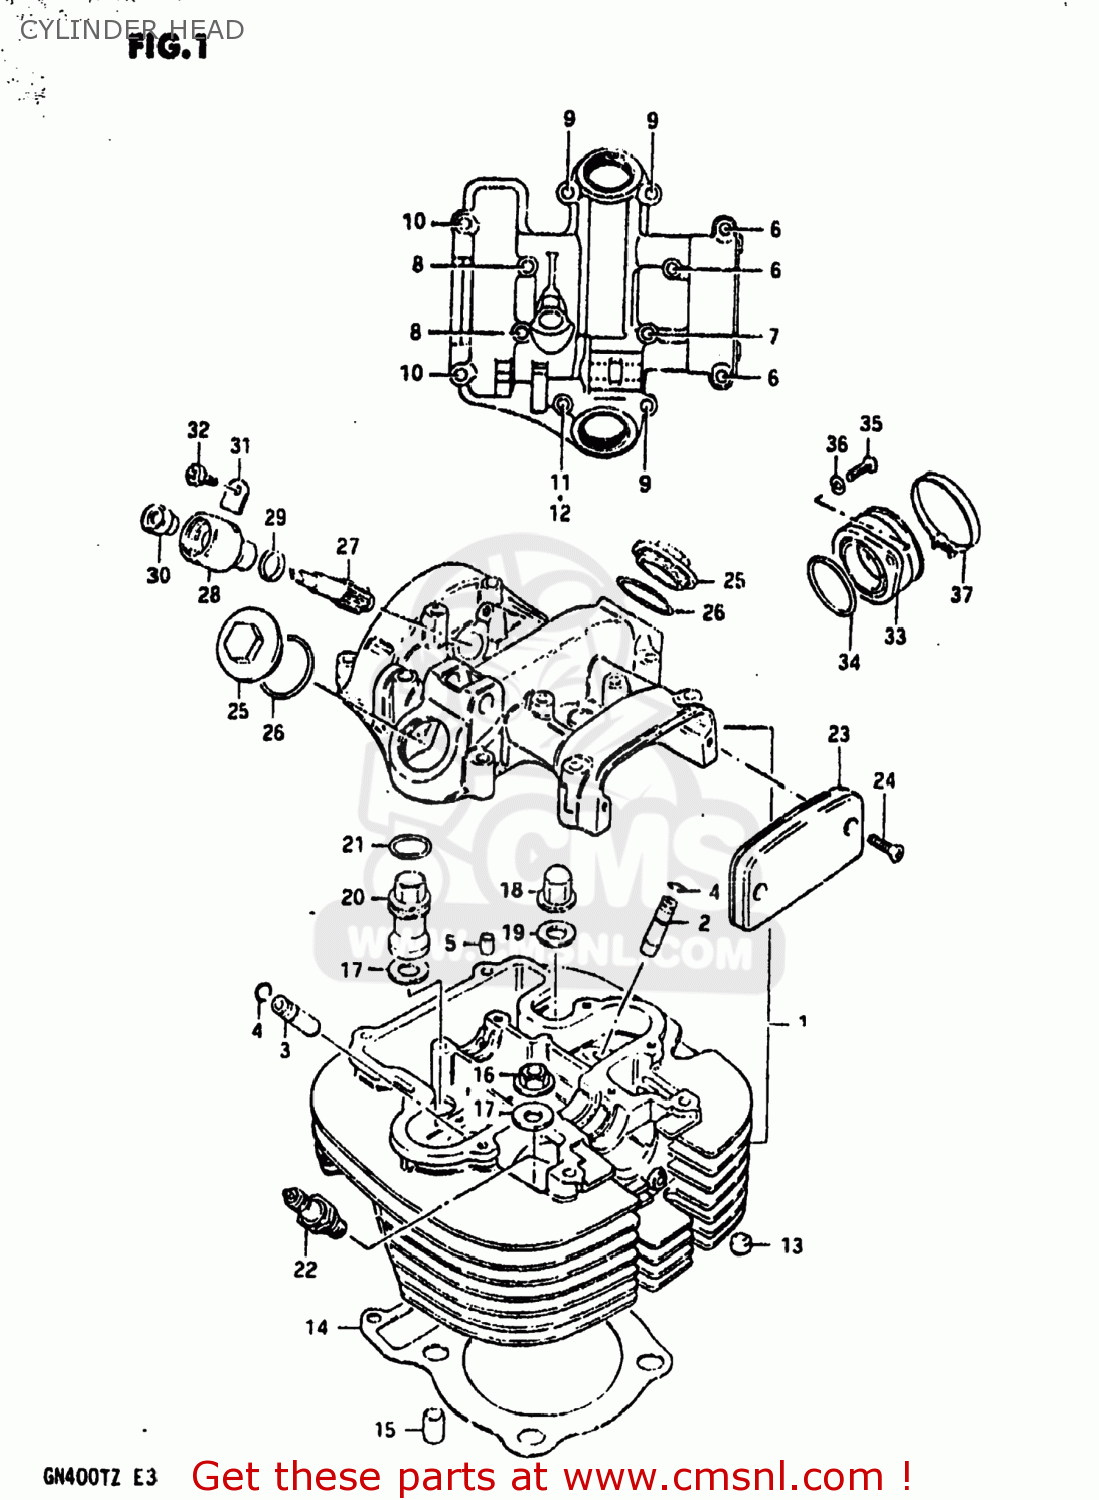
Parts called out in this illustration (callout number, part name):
1	HEAD,CYLINDER
2	GUIDE,INTAKE VALVE
3	GUIDE,EXHAUST VALVE
4	RING,SNAP
5	PIN(6.2X8X11)
6	BOLT ,6X50
7	BOLT
8	BOLT 6X65
9	BOLT 6X35
10	BOLT(6X125)
11	BOLT (6X60)
12	GASKET (NAS)
13	PAD,CYLINDER
14	GASKET,CYLINDER HEAD (NAS)
15	PIN
16	NUT
17	WASHER(10.5X22X2.3)
18	NUT
19	GASKET (NAS)
20	NUT,CYLINDER HEAD SEAL
21	O RING(D:2.4,ID:17.8)
22	SPARK PLUG D8EA
23	CAP,CYLINDER HEAD COVER
24	SCREW
25	CAP,INSPECTION
26	O RING(D:3,ID:29.5)
27	GEAR,TACHOMETER DRIVEN
28	SLEEVE,TACHOMETER DRIVE
29	SEAL,TACHOMETER DRIVEN
30	SEAL,OIL(5X12X8)
31	PLATE,TACH DRIVE GEAR SLEEVE
32	SCREW(5X12)
33	PIPE,INTAKE
34	O-RING (D:2.4 ID:39.7)
35	SCREW
36	LOCK WASHER
37	CLAMP
